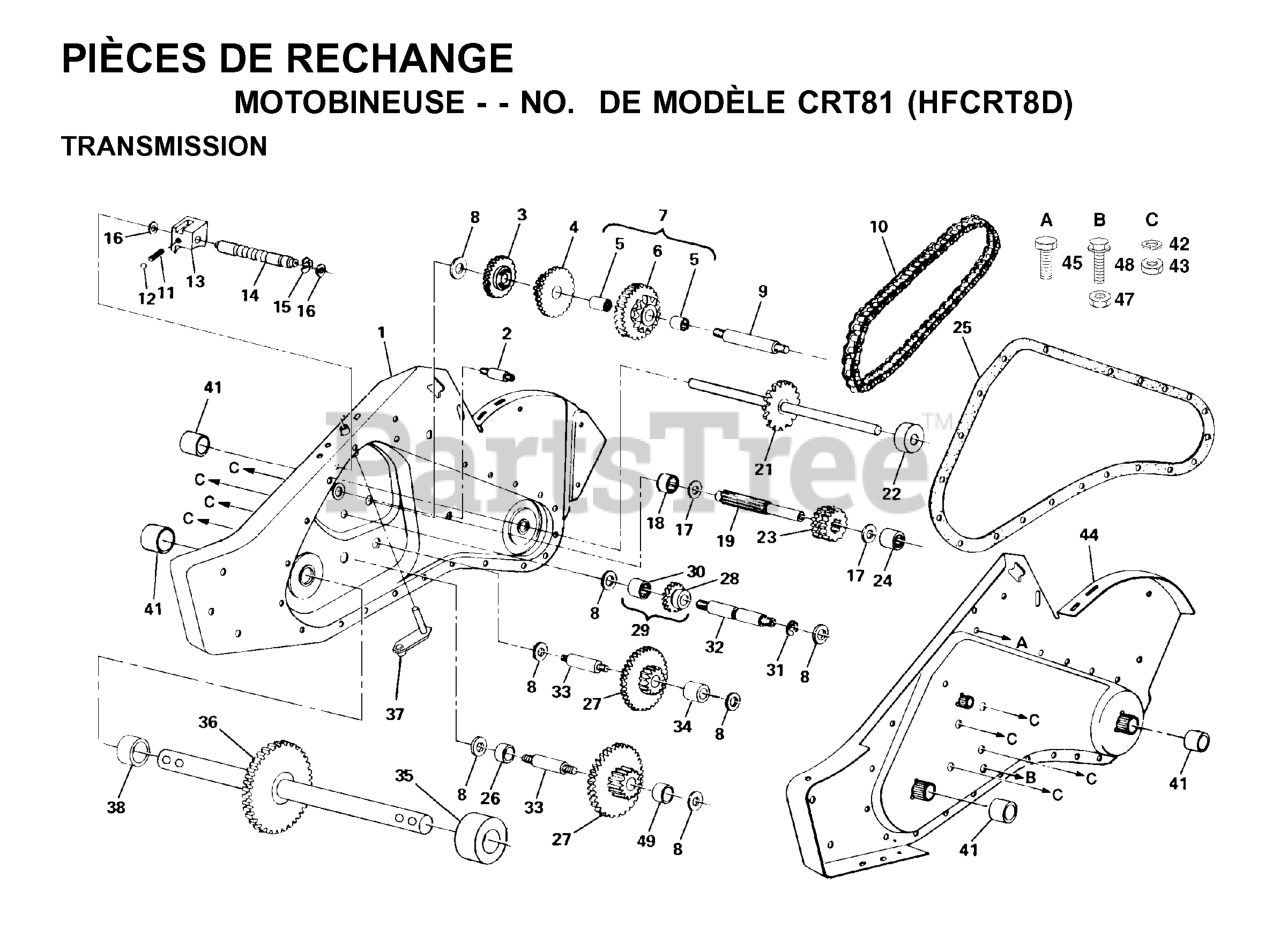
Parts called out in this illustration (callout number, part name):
1	GAERCASE.ASM.RH.W/BEARING
3	GEAR, REVERSE
4	GEAR, CLUSTER (2 GEAR SET)
5	BEARING.NEEDLE.CRT
6	SPROCKET ASMBLY, TINE
7	SPROCKET ASMBLY W/BEARINGS
9	SHAFT.REDUCTION.TILLER
10	CHAIN.ROLLER.TILLER
11	SPRING-SHIFT CRT
12	STEEL BALL KIT
13	SHIFT FORK TI
14	SHAFT, SHIFT
16	WASHER, SEAL (2 2)
17	THRUST WASHER
18	BEARING TI
19	SHAFT INPUT
21	SHAFT TINE CRT
22	SPACER 1.008X1-3/4X.645
23	PINION, INPUT
24	NEEDLE BRNG LT
25	RP GASKET, GEARCASE
27	GEAR, CLUSTER CRT
28	REVERSE GEAR
29	GEAR ASMBLY, REVERSE IDLER
30	NEEDLE BEARING TI
32	SHAFT, REVERSE IDLER
33	SHAFT, REDUCTION
34	SPACER.765 X 1.12 X .380.
35	SPACER, GROUND DRIVE RH
36	SHAFT ASSY CRT
37	BRACKET ASM.SHIFT.CRT
38	SPACER, GROUND DRIVE
41	SEAL ASM, OIL
42	LOCKWASHER
43	NUT.ASF.HEX.7/16
44	GEARCASE ASM, LH
45	SCREW
48	SCREW 5/16-18X4
